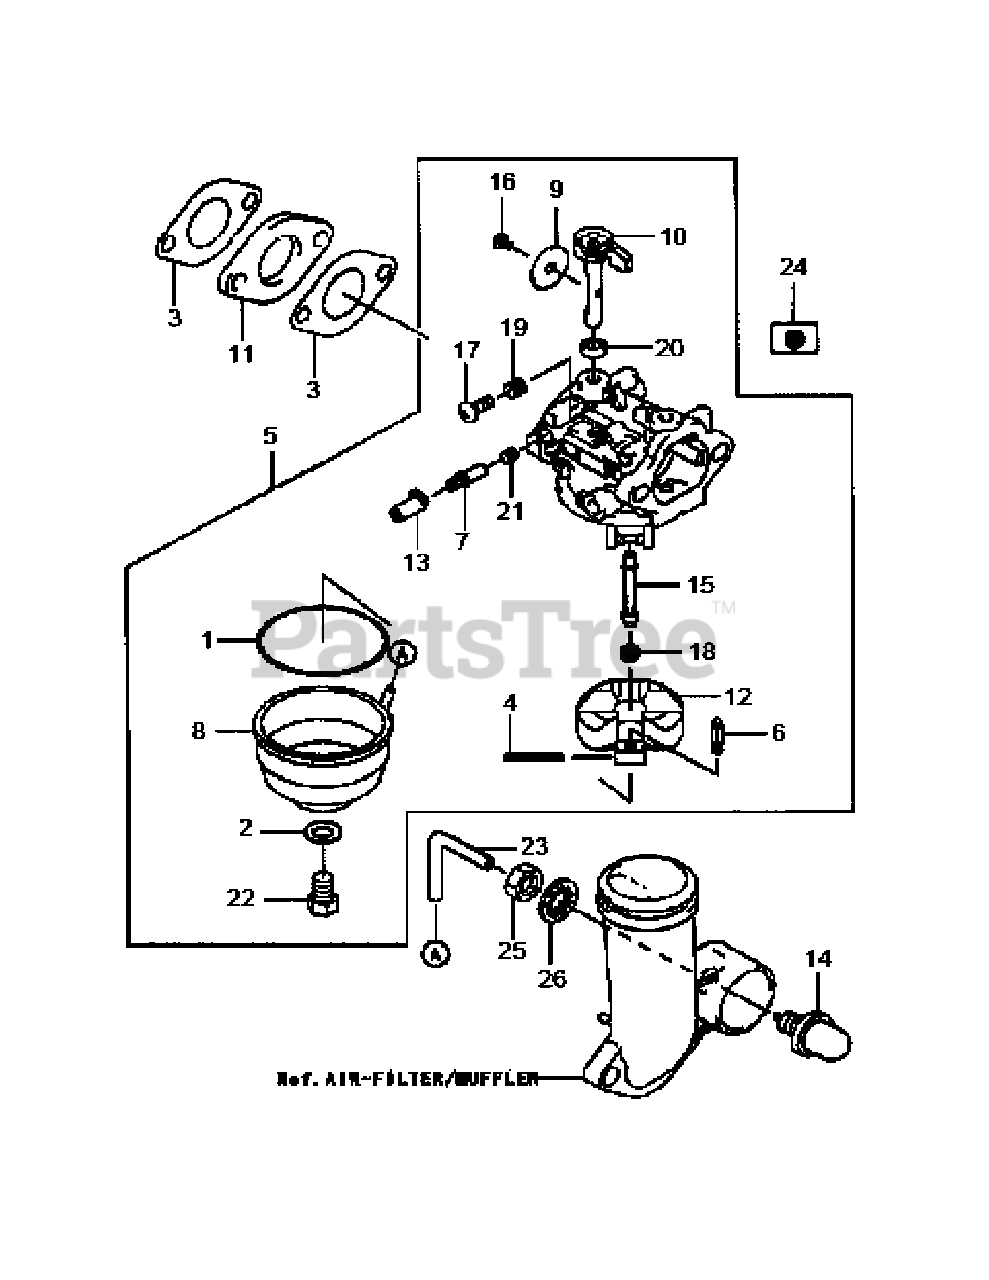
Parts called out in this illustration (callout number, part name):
3	Gasket
5	Carburetor Assy.
7	Pilot Air Screw
8	Float Chamber
9	Throttle Valve
10	Throttle Shaft
11	Insulator
18	Main Jet, #76
23	Tube, 2x5x65
25	Hex Nut, Fine
26	Toothed Washer
